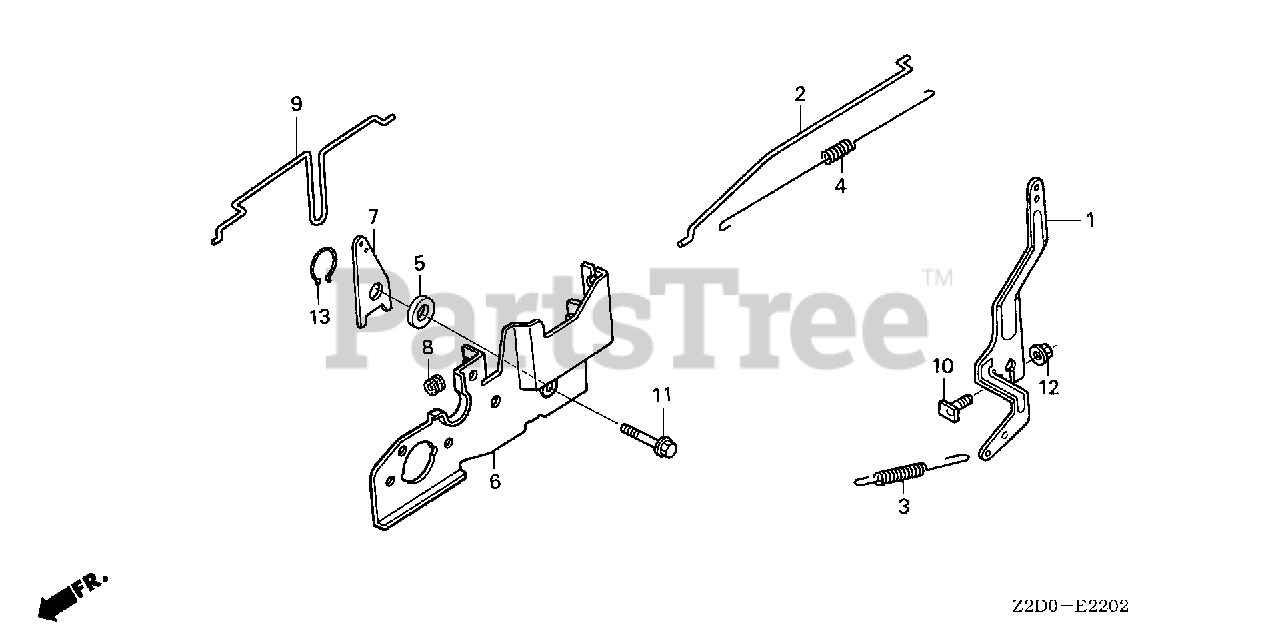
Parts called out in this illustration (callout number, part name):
1	ARM, GOVERNOR
2	ROD, GOVERNOR
3	SPRING, GOVERNOR
4	SPRING, THROTTLE RETURN
5	SPACER, CONTROL LEVER
6	BASE, CONTROL
7	LEVER, CHOKE
8	GROMMET, CHOKE ROD
9	ROD, CHOKE
10	BOLT, GOVERNOR ARM
11	BOLT, FLANGE (6X45) (CT200)
12	NUT, FLANGE (6MM)
13	CIRCLIP (OUTER) (14MM)
